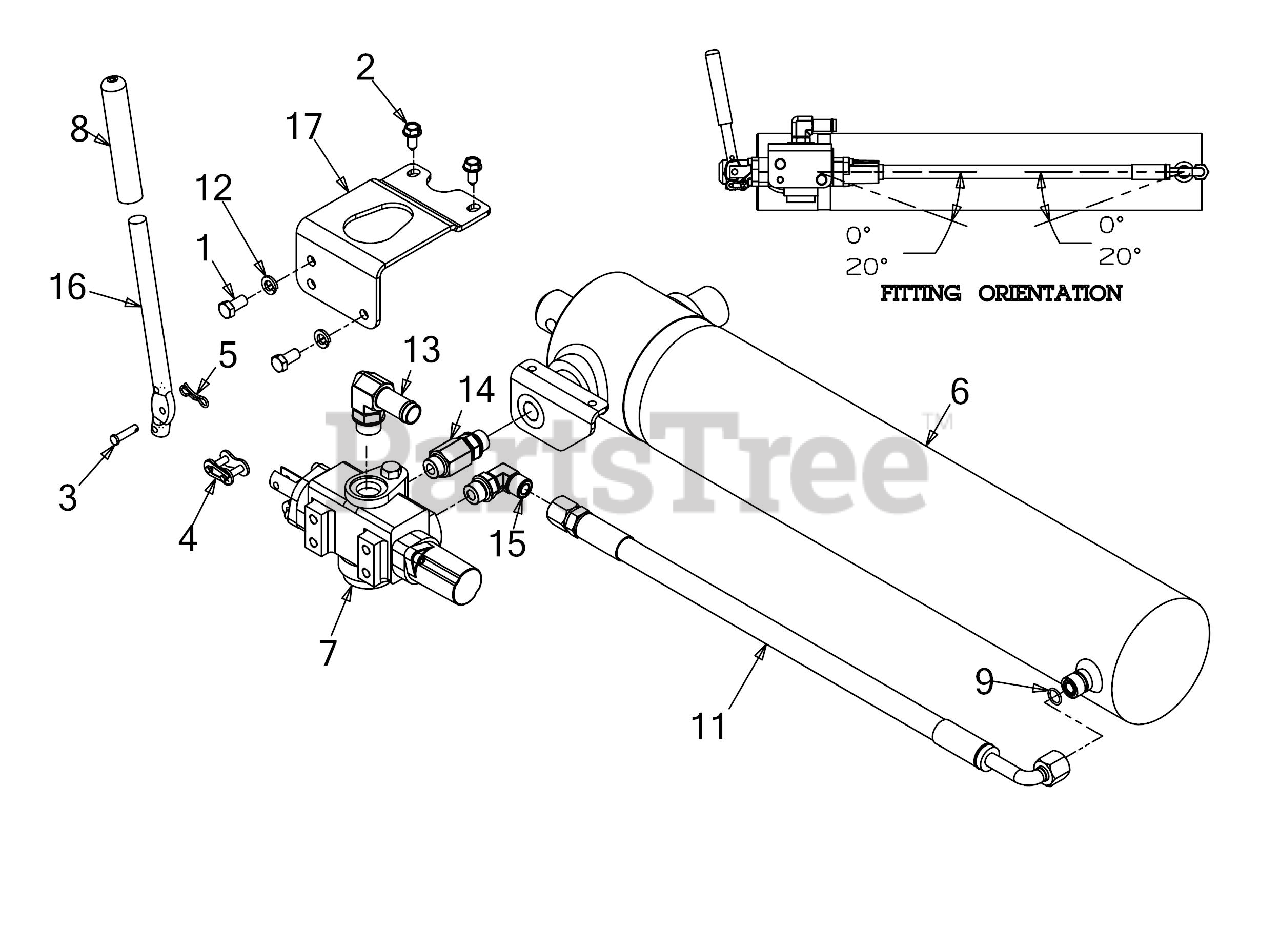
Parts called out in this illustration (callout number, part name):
1	HEX SCREW 3/8-16 x .75
2	SCREW 5/16-18 x .750
3	CLEVIS PIN .25 x 1.00
4	VALVE HANDLE LINK
5	BOW TIE COTTER PIN 1/4-5/16
6	HYDRAULIC CYLINDER
7	LOGSPLITTER VALVE
11	HYDRAULIC HOSE
12	LOCK WASHER 3/8
13	HYDRAULIC FITTING
14	HYDRAULIC FITTING
15	HYDRAULIC FITTING
16	CONTROL VALVE HANDLE
17	VALVE BRACKET
